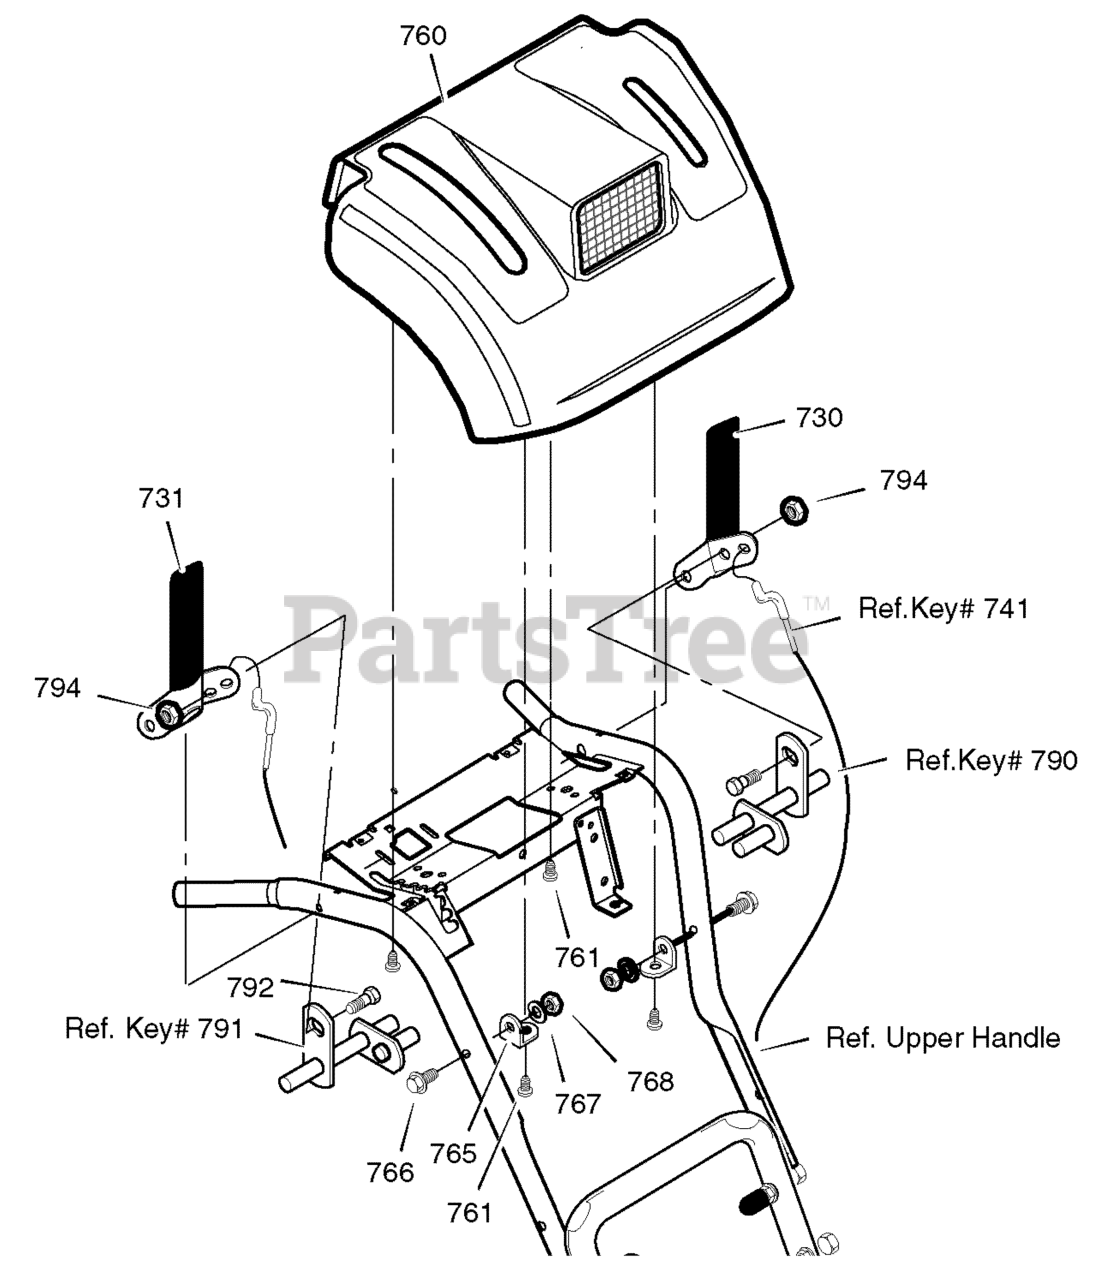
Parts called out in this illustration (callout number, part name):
730	CLUTCH HANDLE LH
731	CLUTCH HANDLE RH
760	PANEL, CONTROL
761	SCREW, 10 X .62
765	BRACKET, PANEL
766	SCREW, 5/16-18 x 1.75
767	WASHER
768	NUT, 5/16-18
792	BOLT, 1/4-20 X .50
794	NUT, 1/4-20
